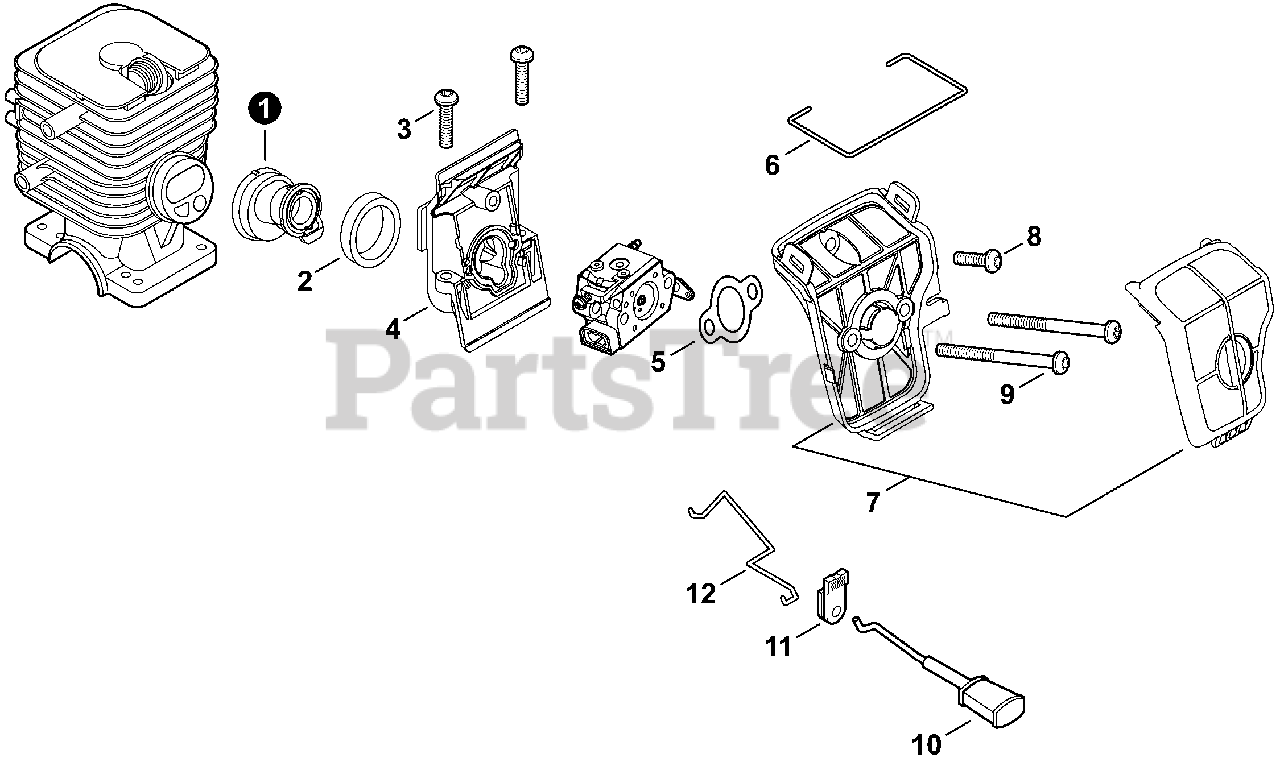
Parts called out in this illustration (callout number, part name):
1	BELLOWS, INTAKE
2	RETAINER, BELLOWS
3	BOLT, TORX 5×20
4	INSULATOR, INTAKE
5	GASKET, INTAKE
6	RETAINER, AIR FILTER
7	FILTER KIT, AIR
8	BOLT, TORX 5×16
9	BOLT, TORX 5×55
10	ROD, CHOKE
11	GROMMET, CHOKE
12	ROD, THROTTLE
